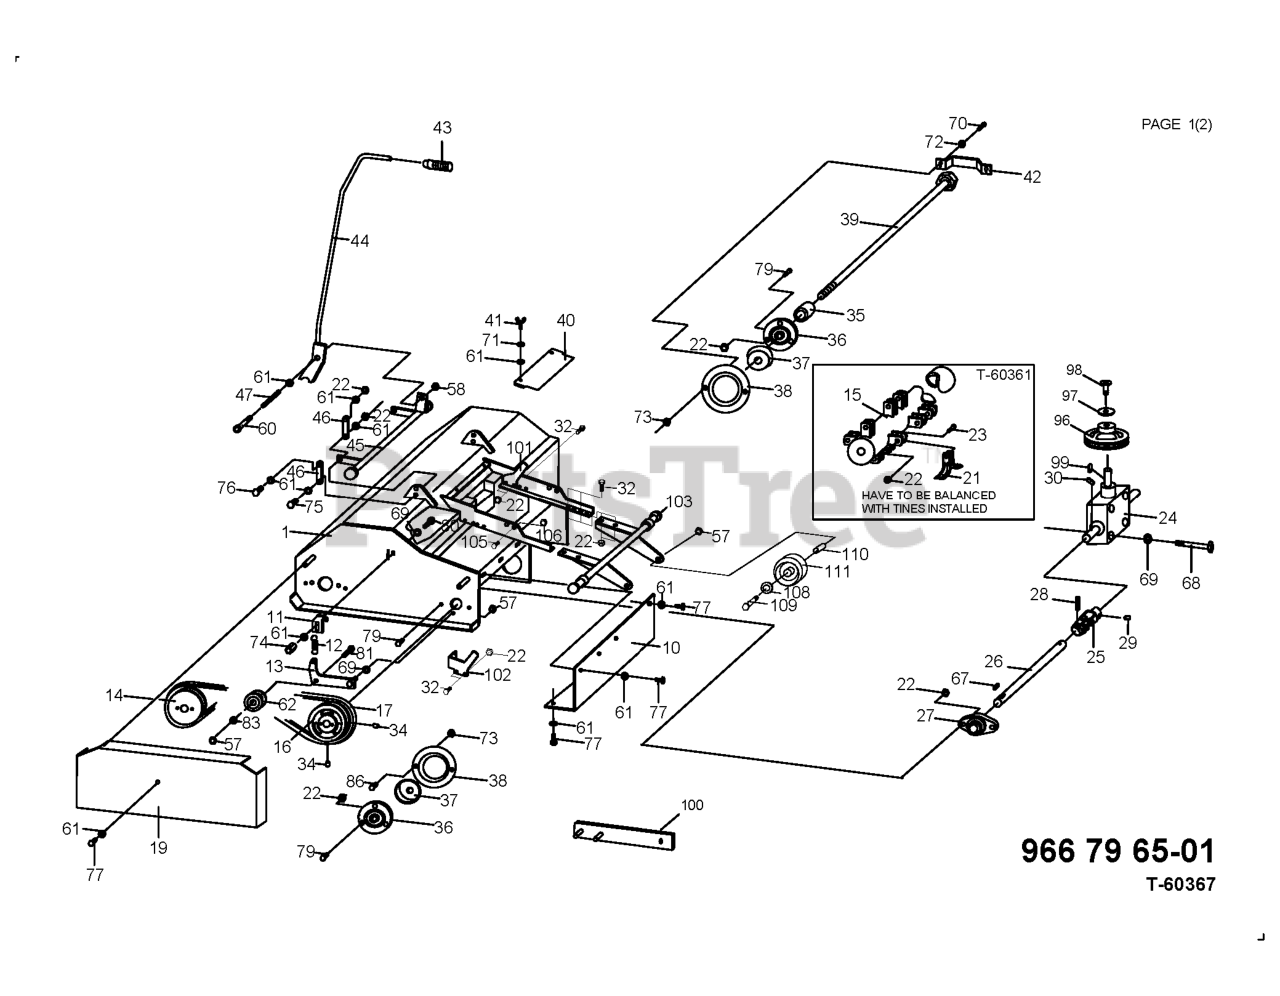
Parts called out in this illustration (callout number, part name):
43	GEAR STICK KNOB
110	COLLAR
111	SUPPORT WHEEL
